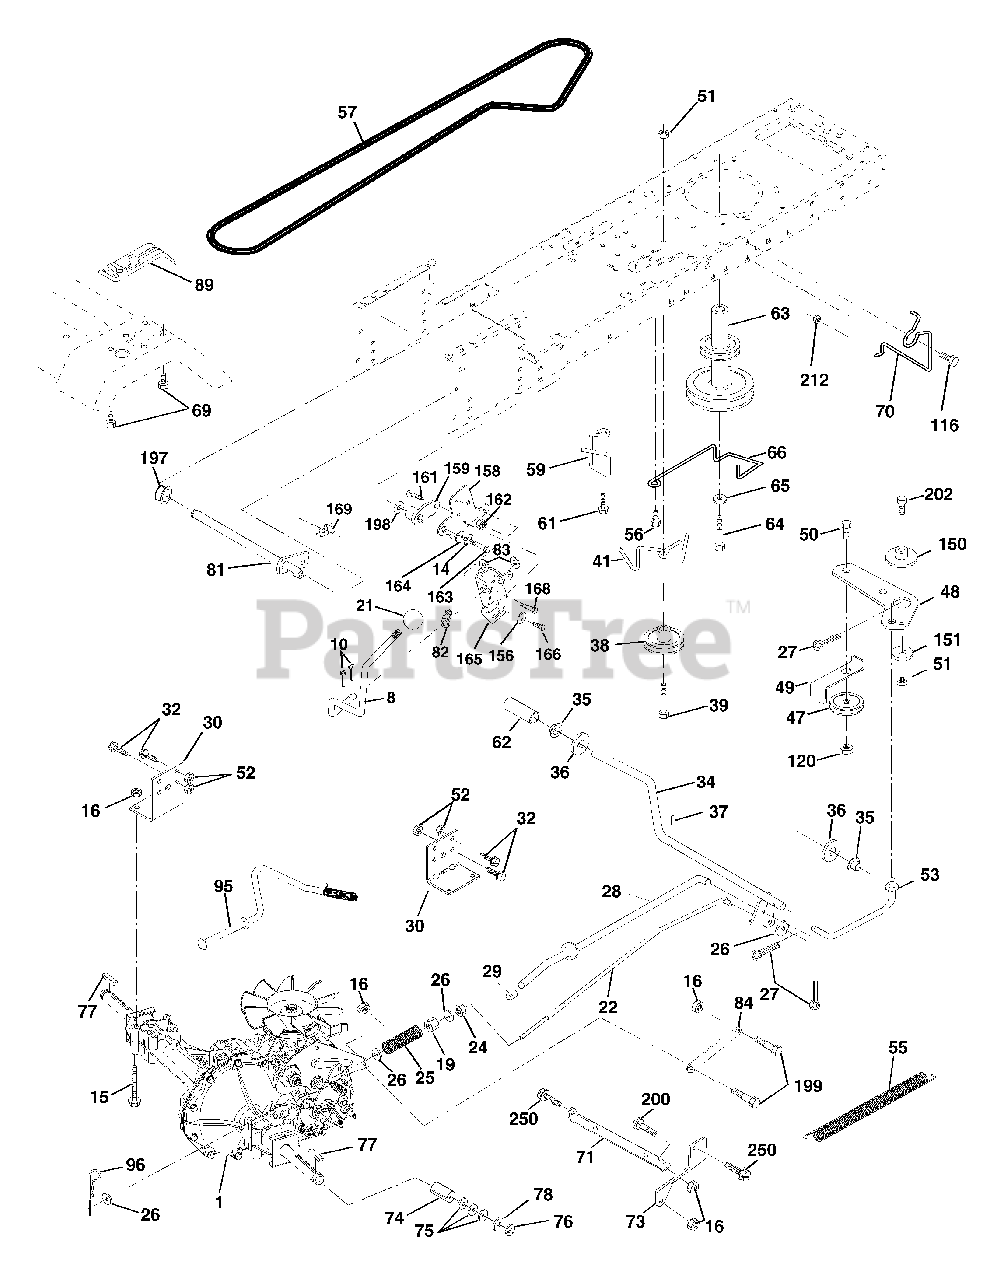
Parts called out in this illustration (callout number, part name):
8	Rod Shift Hydro LT
10	Pin Cotter 1/8 x 1 CAD
14	Washer Lock Hvy Helical
15	Bolt, Hex FLGHD 5/16-18 Gr. 5
16	Nut Lock Hex W/Ins 5/16-18 Unc P
19	Nut Lock Hex W/Wsh 3/8-16 Unc
21	Knob, Round 1/2-13
22	Rod, Brake Hydro
24	Nut
25	Spring, Brake Rod
26	Washer
27	Pin Cotter 1/8 x 3/4 CAD.
28	Rod, Parking Brake
29	Cap, Parking Brake
30	Bracket, Transaxle
32	Bolt Hex Hd 5/16-18 Unc x 3/4
34	Shaft, Foot Pedal
35	Bearing, Nylon
36	Washer
37	Pin, Roll
38	Pulley, Flat Composite
39	Bolt Fin Hex 3/8-16 x 3
41	Keeper, Belt Idler
47	Pulley, Idler, V-Groove
48	Bellcrank Clutch Grnd Drv STL
49	Retainer, Belt
50	Bolt
51	Nut Crownlock 3/8-16 UNC
52	Nut Crownlock 5/16-18 UNC
53	Link, Clutch
55	Spring, Return, Clutch
56	Screw 3/8-16 x 1-1/4
57	V-Belt, Ground Drive
59	Keeper, Center Span
61	Screw 3/8-16 x .875
62	Cover, Pedal
63	Pulley, Engine
64	Bolt, Hex
65	Washer
66	Keeper Belt Engine
69	Screw
70	Guide Belt
71	Strap Torque Lh Hydro
73	Strap Torque Rh Hydro
74	Spacer, Axle
75	Washer 25/32 x 1-1/4 x 16 Gauge
76	E-Ring
77	Key, Square
78	Washer 25/32 x 1-5/8 x 16 Gauge
81	Shaft Asm. Cross Hydro
82	Spring Torsion T/A
83	Washer 17/32 x 3/4 x 16 Ga.
84	Link Transaxle
89	Console, Hydro
95	Control Asm Bypass Hydro
96	Retainer Spring 1" Zinc/Cad
116	Bolt Rdhd Sq Neck 3/8-16 x 1
120	Nut Lock Flg 3/8-16
150	Spacer Retainer
151	Washer 13/32 x 2 x 10 Ga.
156	Washer Srrted 5/16 ID x 1.125
158	Bracket Shift Mount
159	Hub Tapered Flange Shift Lt
161	Bolt Rdhd Sqnk 1/4-20 x 3/4 Gr 5
162	Nut Crownlock 1/4-20 Unc
163	Bolt Hex Fin 1/4-20 Unc x 1 Gr 5
164	Washer 5/8 x .281 x 10 Ga
165	Bracket Pivot Lever
166	Screw 5/16-18 x 5/8
168	Bolt Shoulder 5/16-18 x .561
169	Plate Fastening Lt
197	Nyliner Snap-In 5/8" ID
198	Washer Nyl 7/8 ID x .105
199	Bolt Shoulder 5/16-18 Unc
200	Bolt Rdhd Sqnk 5/16-18 Unc x 1
202	Bolt RDHD 3/8-16 x 1-3/4 Gr 5
212	Nut Hex Flg Lock
250	Screw Thdrol. 3/8-16 x .75
